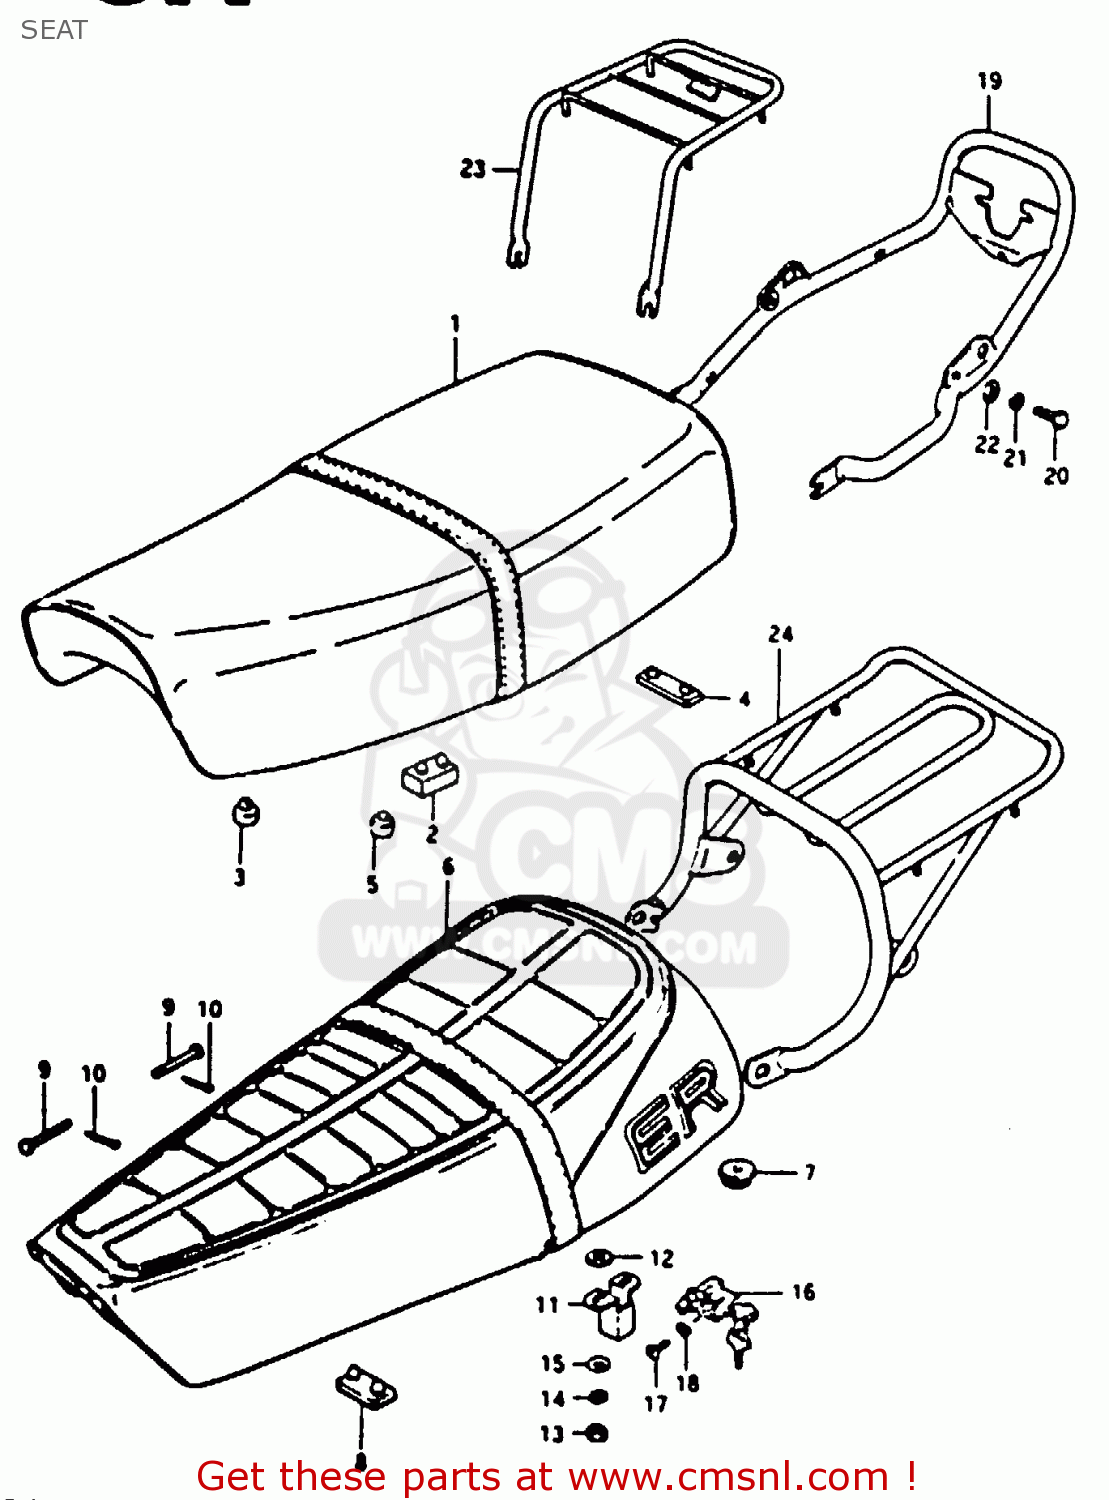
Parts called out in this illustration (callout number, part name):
1	SEAT ASSEMBLY
2	CUSHION
3	CUSHION(11.5X22X20)
4	CUSHION
5	CUSHION
6	7
7	8
8	9
9	PIN
10	PIN
11	PLATE,CLAMP GUIDE
12	WASHER(8.5X18X1)
13	NUT
14	LOCK WASHER
15	WASHER
16	LOCK ASSY,SEAT
17	SCREW
18	LOCK WASHER
19	BAR, REAR COMBINATION LAMP
20	BOLT
21	LOCK WASHER
22	WASHER
23	CARRIER
